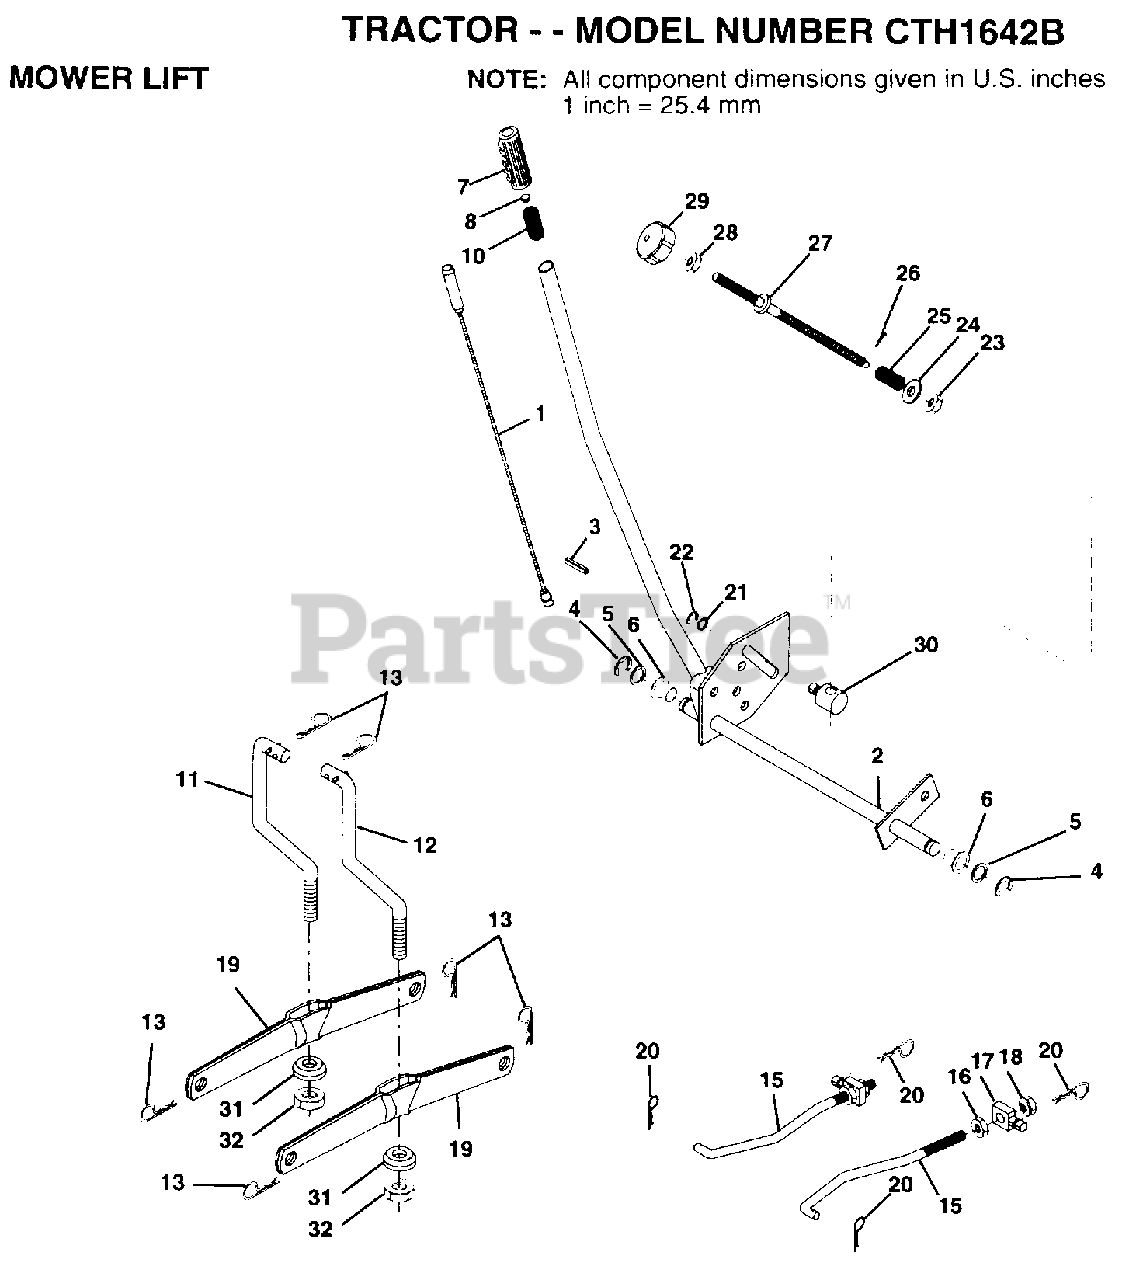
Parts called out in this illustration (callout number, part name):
1	WIRE ASM
2	SHAFT.ASM.LIFT
3	PIN GROOVE
5	WASHER
6	NYLON BEARING
7	GRIP
15	LINK.FRONT
16	NUT
17	TRUNION
18	NUT.LK.W/WSH.1/2.
19	ARM SUSP REAR
20	RETAINER.SPRING
21	WASHER
22	KLIP RING
23	NUT T
24	WASHER
25	SPRING.COMP.INF.H
27	ROD.ADJ.LIFT
28	NUT
29	KNOB INF 3/8-16
30	TRUNION LT
31	BEARING PVT LH
32	NUT.CROWNLOCK.3/8
